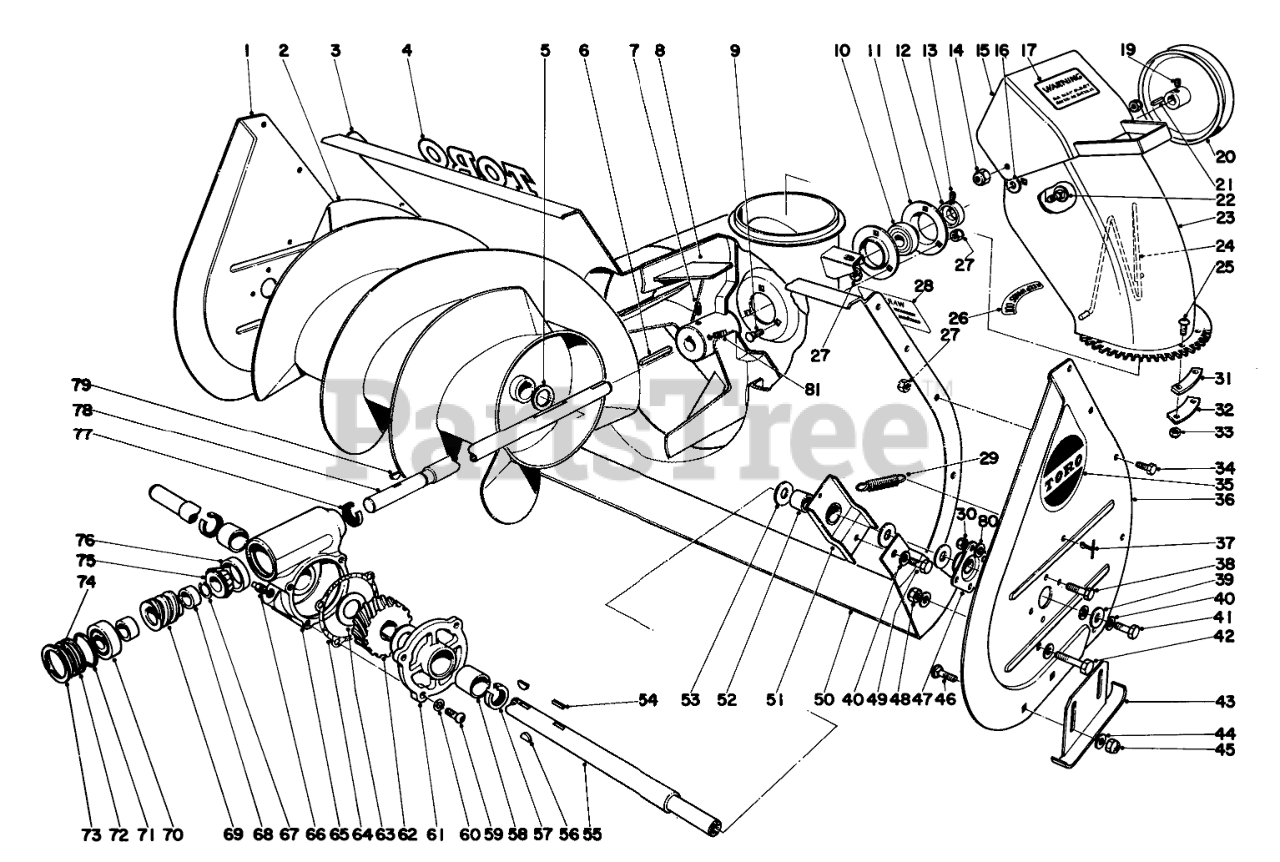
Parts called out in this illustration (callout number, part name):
1	Side Plate
2	Auger, R.H.
3	Auger Housing
4	Decal
5	Spacer
7	SCREW-SET, SQH
8	Impeller
9	BOLT-CARR
10	BALL BRG W/COLLAR
11	BRG FLANGE
12	EXT LOCKING COLLAR
13	SCREW-HSH
14	NUT-LOCK, NI
15	Deflector
16	WASHER-FLAT
17	Decal
18	NUT-LOCK, NI
19	SCREW-SET, SQH
20	1/2 X 9.5 DIA PULLEY
21	SQUARE KEY
22	SCREW-CARR
23	Upper Chute
24	Chute Wire
25	SCREW-HSBH
26	Decal
27	Nut
28	Decal
29	SPRING-TENSION
30	NUT-LOCK
31	CHUTE TAB SPACER
32	UPPER CHUTE TAB
33	Nut
34	SCREW-HH
35	Decal, Auger Sideplate
36	Side Plate L. H.
37	Retainer Spring
38	SCREW-HH
39	WASHER
40	WASHER-LOCK
41	SCREW-HH
42	SCREW-HH
43	Skid
44	WASHER-FLAT
45	NUT-LOCK, NI
46	BOLT-CARR
47	Bearing Flange
48	NUT-HEX
49	SCREW-HH
50	Scraper Blade
51	Scraper Blade (Incl. Ref. No. 52)
52	BUSHING
53	WASHER-THRUST
55	Auger Shaft
56	KEY-WOODRUFF
57	SEAL-OIL
58	Bushing
59	SCREW-HSBH
60	WASHER-LOCK
61	Cover, Gear Box (Incl. Ref. No. 58)
62	GEAR-WORM, 27T
63	WASHER-THRUST
64	Gasket
65	Gear Box (Incl. Ref. Nos. 58 & 76)
66	PLUG-PIPE, SQH
67	13 Snap Ring
68	Spacer
70	.750 BALL BEARING
71	O-RING
73	INTRNL RETAINING RING
75	3/4 ROLLER BRG CONE
76	1.750 ROLLER BRG CUP
77	SEAL-OIL
78	Shaft Worm
79	KEY-WOODRUFF
80	WASHER-FLAT
81	SCREW-SET, SQH
